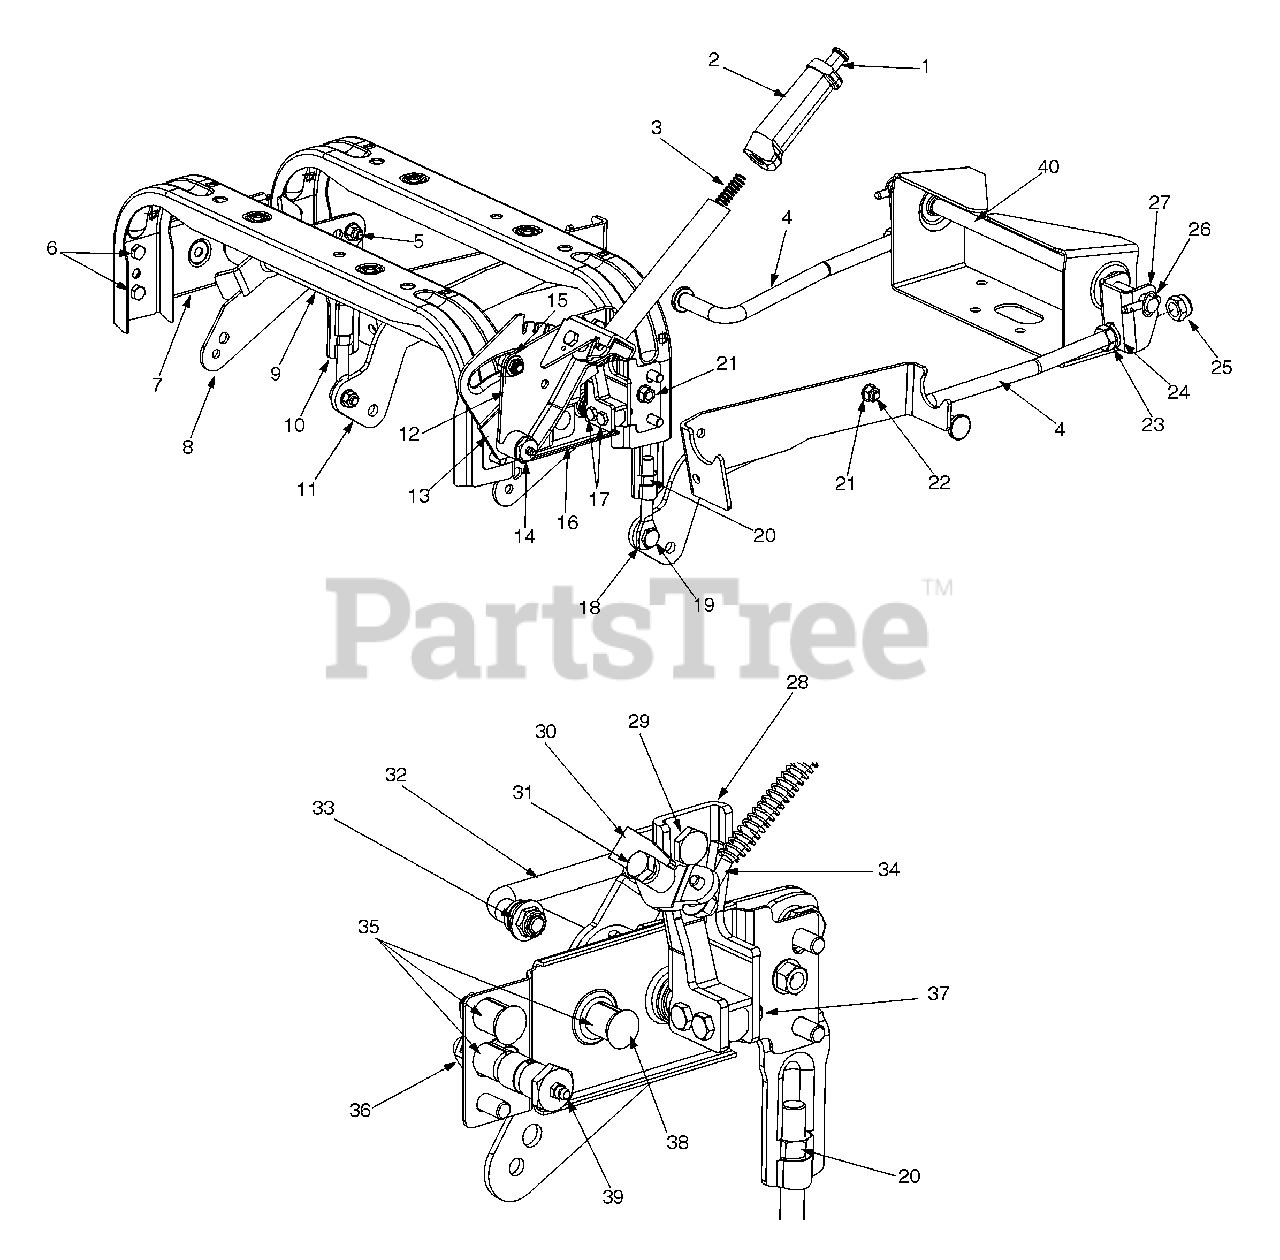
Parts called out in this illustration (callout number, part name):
1	Handle Button
2	Handle Deck Lift Grip
3	Compression Spring
4	Front Lift Rod
5	Shoulder Screw .500 Dia x .434
6	Hex Cap Screw 3/8-16 x .75
7	Shaft Mounting Bracket - LH
15	Top Lock Jam Nut 3/8-16
16	Shaft Mounting Bracket - RH
17	Hex Cap Screw 5/16-18 x 1.375
18	Eye Bolt Adjustable Link
19	Shoulder Screw 3/8-16
20	Hex Nut 1/2-13
21	Flange Lock Nut 3/8-16
22	Shoulder Screw 3/8-16 .56 x .27
23	Jam Nut 5/8-11
24	Lock Washer 5/6
25	Lock Hex Nut 5/8-11
26	Clevis Pin
29	Shoulder Screw 3/8-16 .50 x .21
31	Hex Cap Screw 3/8-16 x 2.25
32	Lift Link Rod
33	Flat Washer .406 x .875
34	Handle Arm
35	Spacer .448 ID x .688 OD
36	Lock Nut 7/16-14
37	Hex Center L-Nut 5/16-18
38	Hex Screw 3/8-16 x 1.50
39	Grease Fitting
40	Front Mounting Rod Bracket
